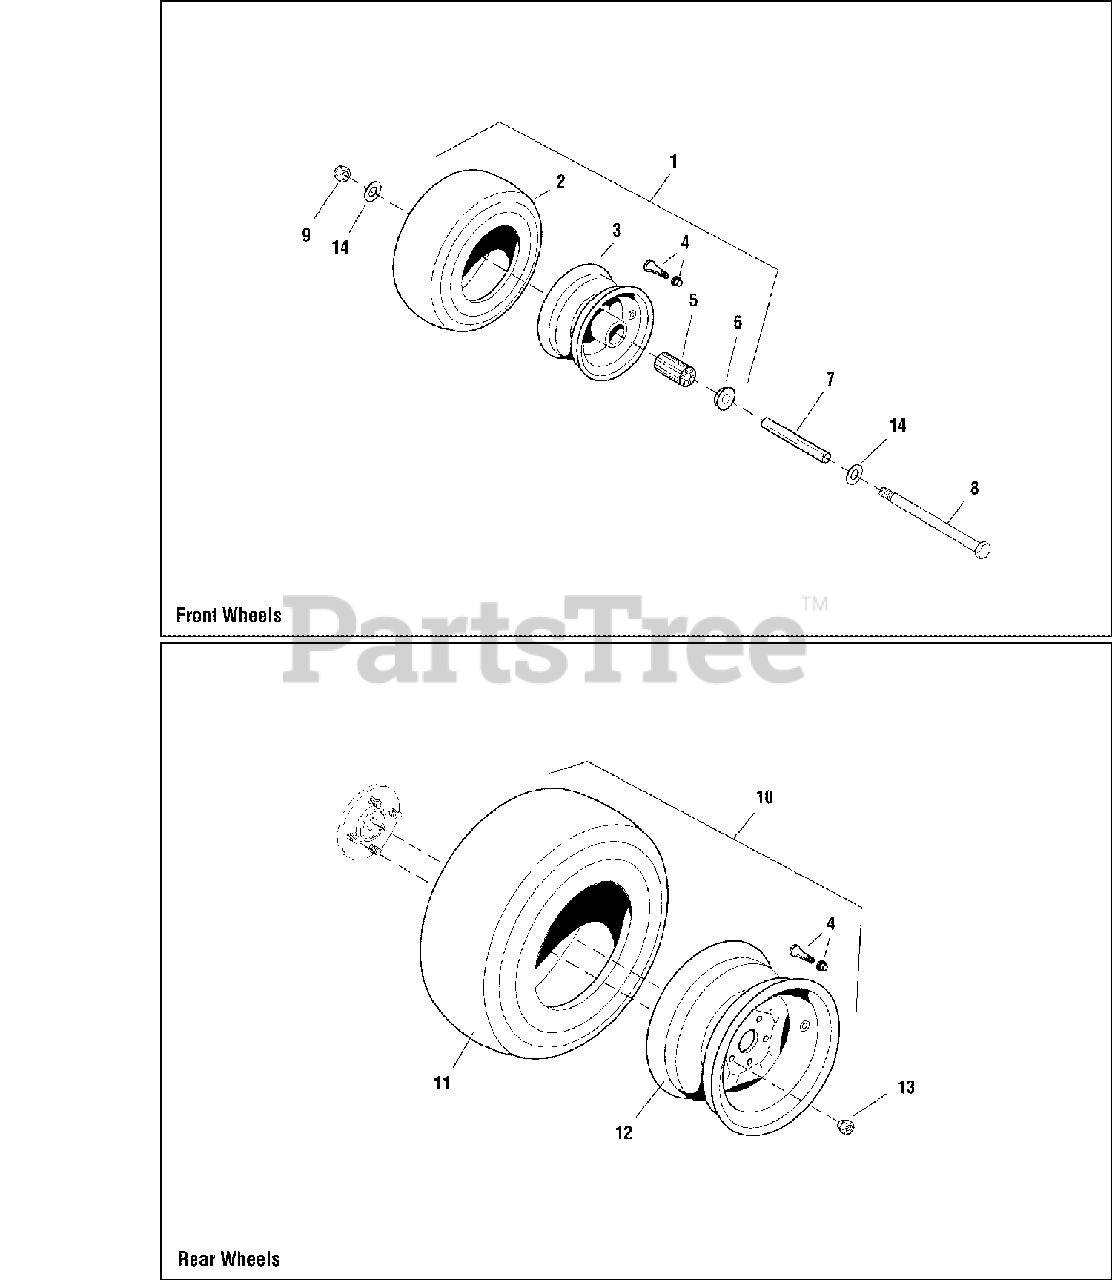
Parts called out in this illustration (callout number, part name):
1	WHEEL & TIRE ASSEMBLY, 11 X 4.0 - 5, COMPLETE
2	TIRE, FRONT, 11 X 4.0 - 5
3	WHEEL ASSEMBLY, COMPLETE
4	VALVE STEM & CAP ASSEMBLY
5	BEARING, ROLLER
6	BEARING RETAINER
7	AXLE, FRONT CASTER
8	BOLT, 1/2-13 X 6-1/2
9	NUT, HEX NYLON LOCK, 1/2-13
10	TIRE ASSM, 20X8.00-10NHS, TM, 2.625 OFFS
11	TIRE, REAR, 20 X 8.0 X 10, TURF MASTER
12	WHEEL ASSEMBLY, FOR 20 X 8.0 X 10 TIRE
13	LUG NUT, 1/2-20
14	WASHER, 1/2 SAE
